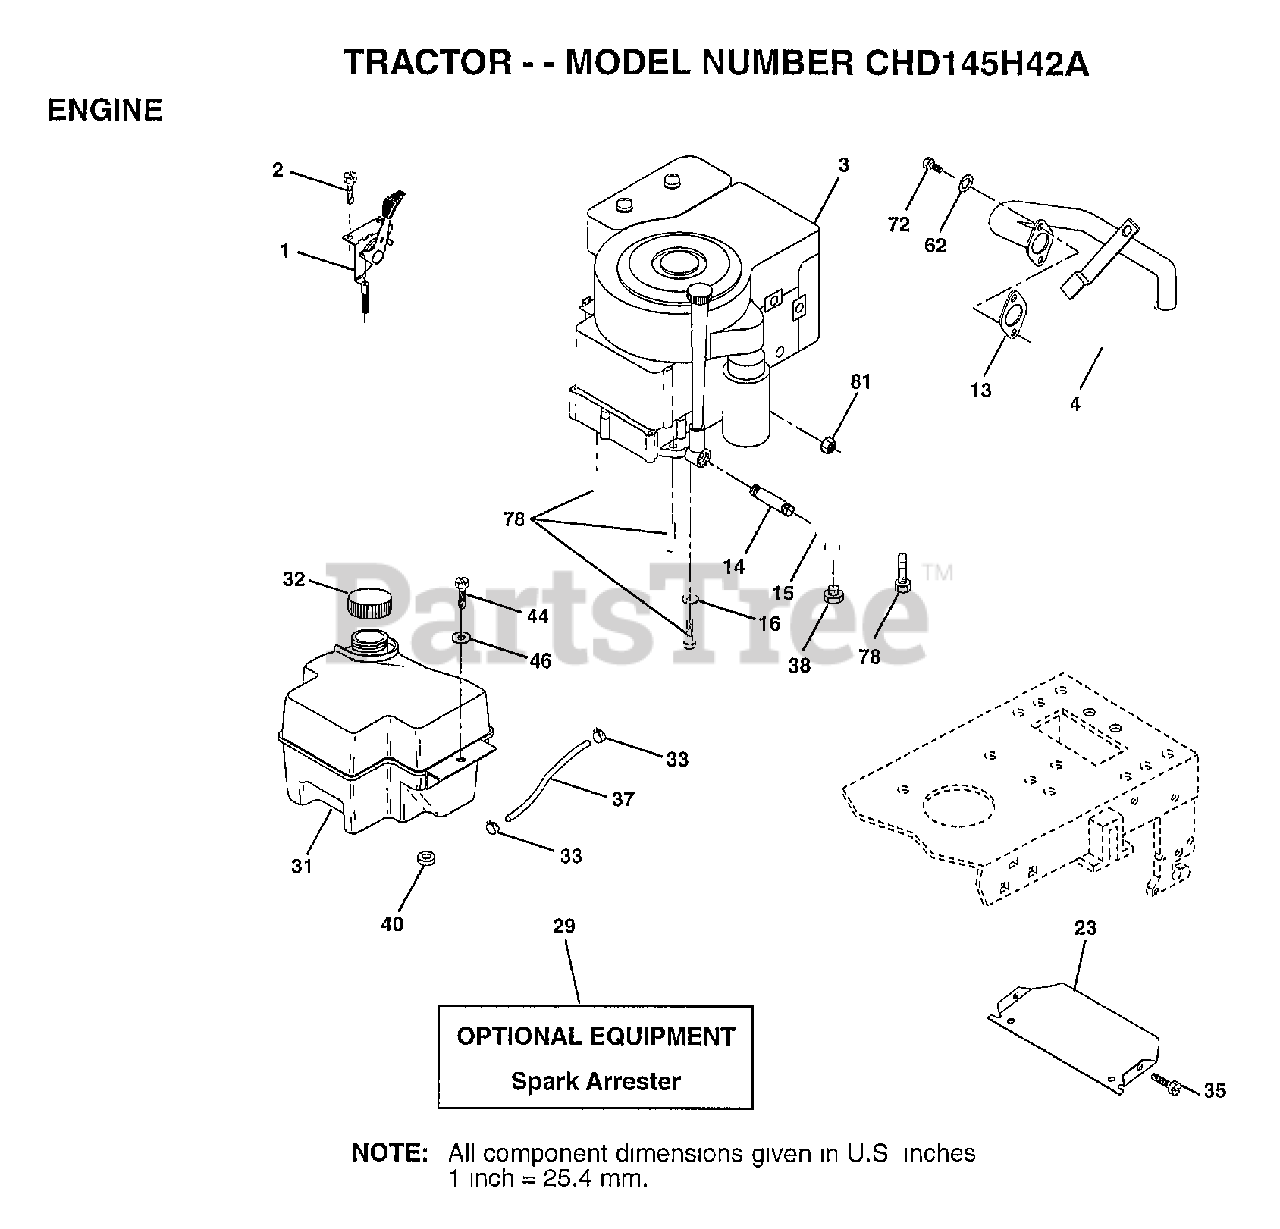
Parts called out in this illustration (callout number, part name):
1	CONTROL THROTTLE
2	SCREW LT
4	MUFFLER
13	GASKET ENG 1 313 LD TIN PLATED
14	PIPE NIPPLE
15	ELBOW
16	LOCKWASHER
23	SHIELD-HEAT
32	CAP ASM FUEL
33	HOSE CLAMP
35	SCREW
37	LINE FUEL
44	SCREW HEX CRT
46	WASHER
62	LOCKWASHER
72	SCREW
78	SCREW
81	NUT
